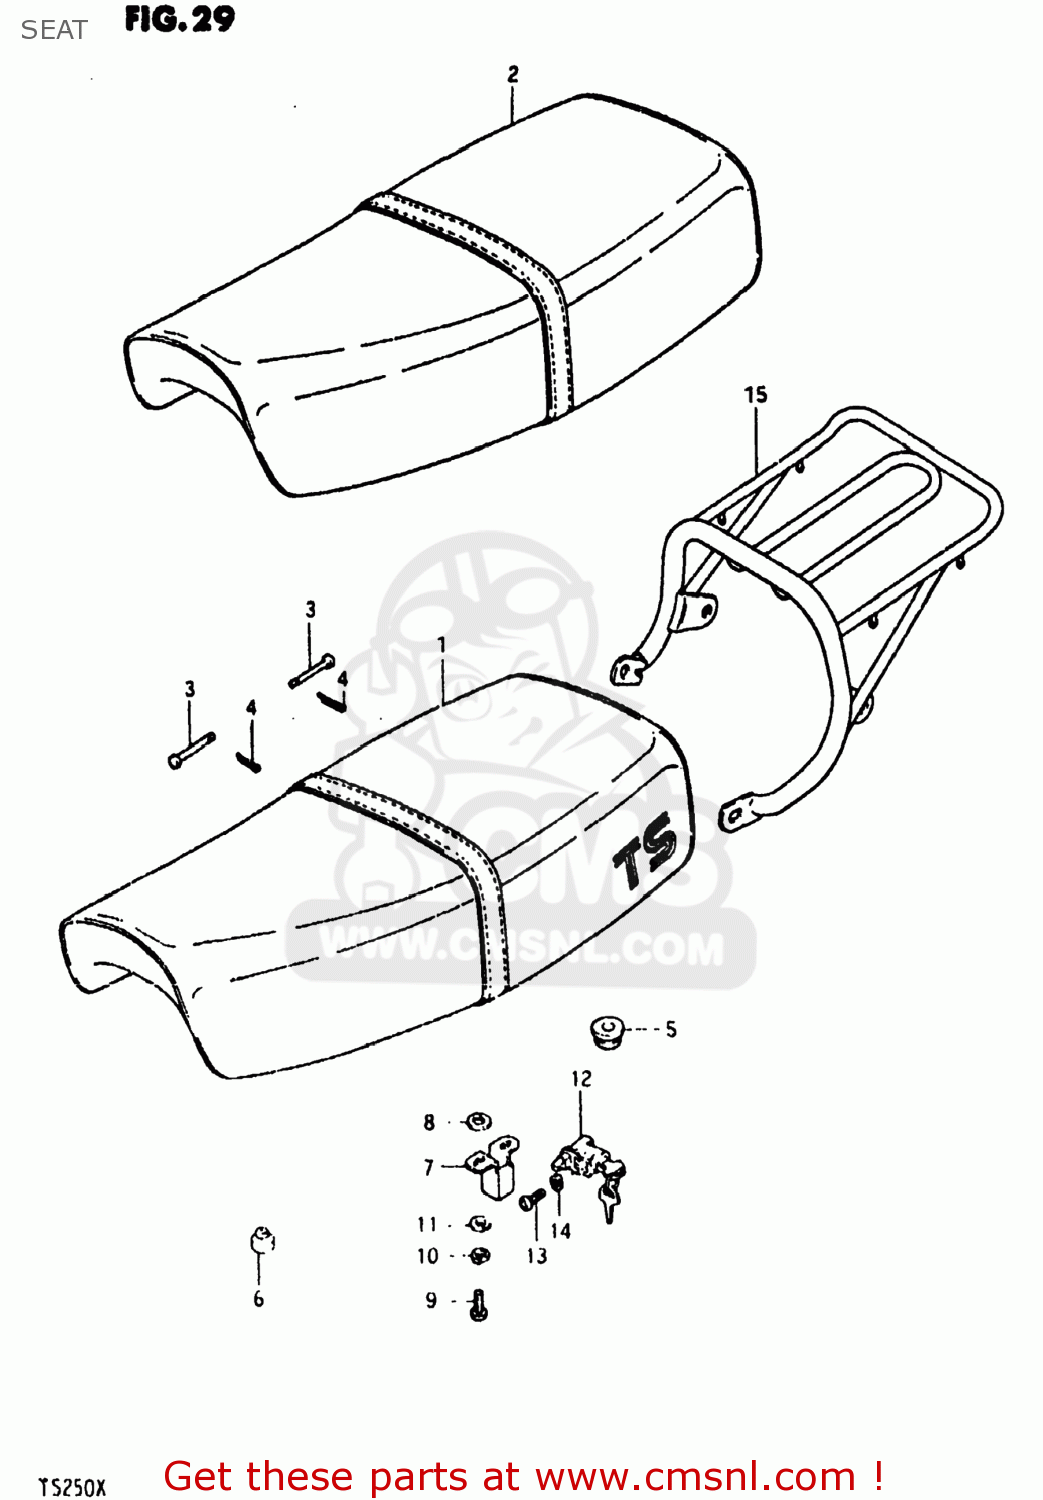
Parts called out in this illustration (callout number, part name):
1	SEAT ASSEMBLY
2	SEAT ASSEMBLY
3	PIN
4	PIN
5	CUSHION
6	CUSHION(11.5X22X20)
7	PLATE,CLAMP GUIDE
8	WASHER(8.5X18X1)
9	SCREW 6X12
10	LOCK WASHER
11	WASHER
12	LOCK ASSY,SEAT
13	SCREW
14	LOCK WASHER
15	CARRIER
